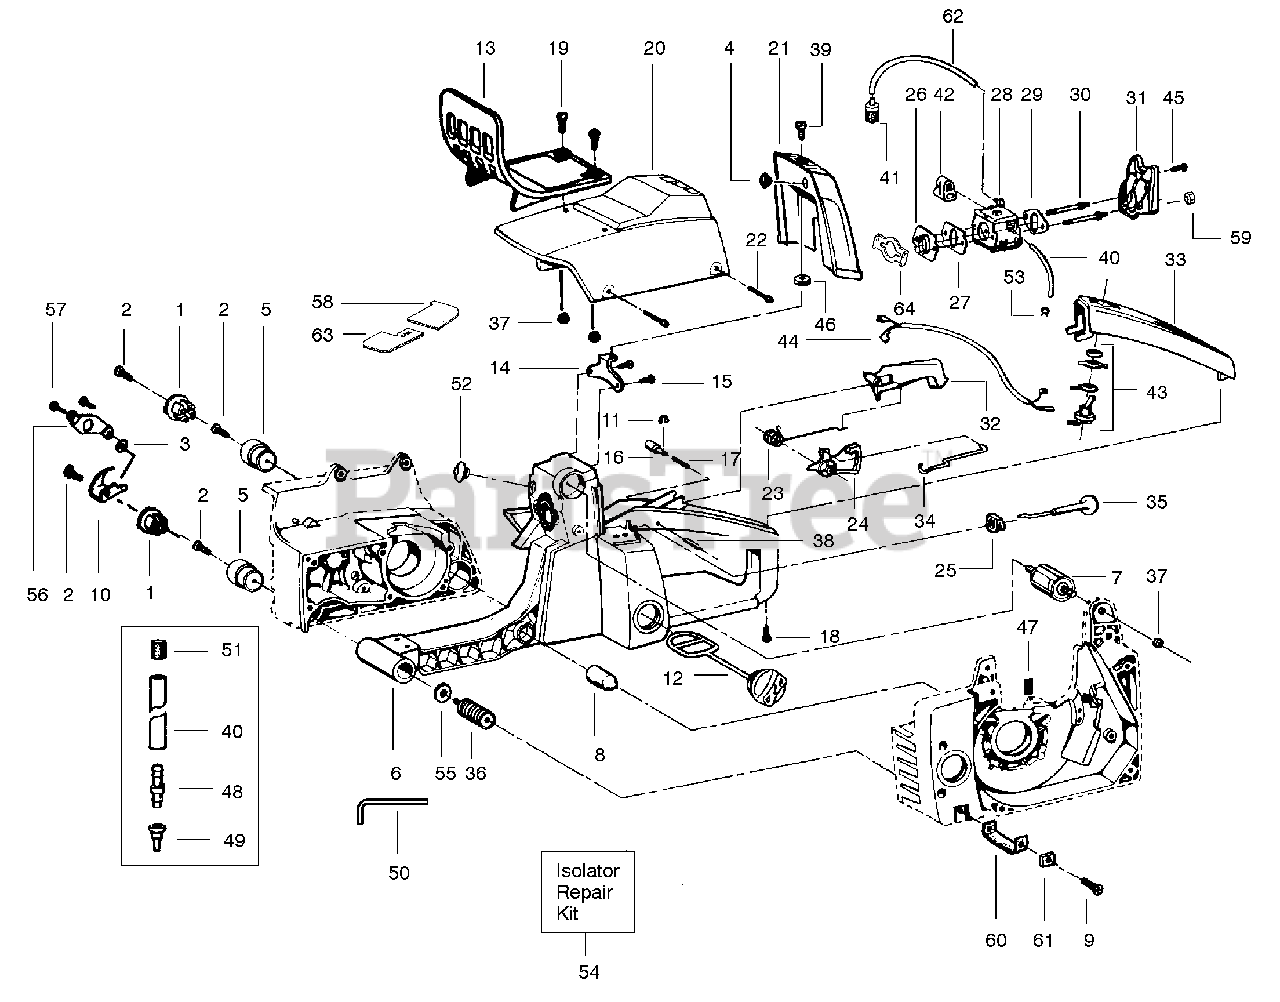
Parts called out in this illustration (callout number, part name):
1	Retainer Chain Catcher
3	Washer-Flat
4	Carb. Cover Bumper
5	Lower Isolator
6	Rear Handle & Fuel Tank
7	Cylindrical Mount
8	Isolator Bumper
9	Screw
10	Chain Catcher
11	"C" Clip
12	Fuel Cap Ass'y.
13	Handguard
14	Bracket-Carb Cover Mount
16	Button Throttle Lock
17	Throttle Spring
20	Cylinder Shield Kit
21	Carb. Cover
22	Screw
23	Trigger Latch Spring
24	Throttle Trigger
26	Bracket-Intake Manifold
27	Gasket Set
28	Carburetor (HDA-49)
29	Air Filter Plate
30	Carb. Mounting Stud
31	Air Filter Ass'y.
32	Throttle Lockout
33	Rear Handle Cover
34	Throttle Wire
35	Choke Knob
36	Isolator Kit
38	Dowel Pin
40	Vent Line Kit
41	Fuel Pickup Ass'y.
42	Grommet-Carb.
43	Switch Kit
44	Lead Wire Ass'y.
45	Screw
46	Retainer-Screw
47	Fitting-Bar Pad
48	Vent Fitting
49	Check Valve
50	Hex Wrench (5/32)
51	Vent Plug
52	Air Box Plug
53	Clamp-Impulse
54	Isolator Repair Kit
56	Bracket Retainer
58	Carb. Seal-Right
59	Nut-Air Filter
60	AV Strap
61	Strap Retainer Plate
62	Fuel Line Kit
63	Carb. Seal-Left
64	Bracket-Carb Stud
